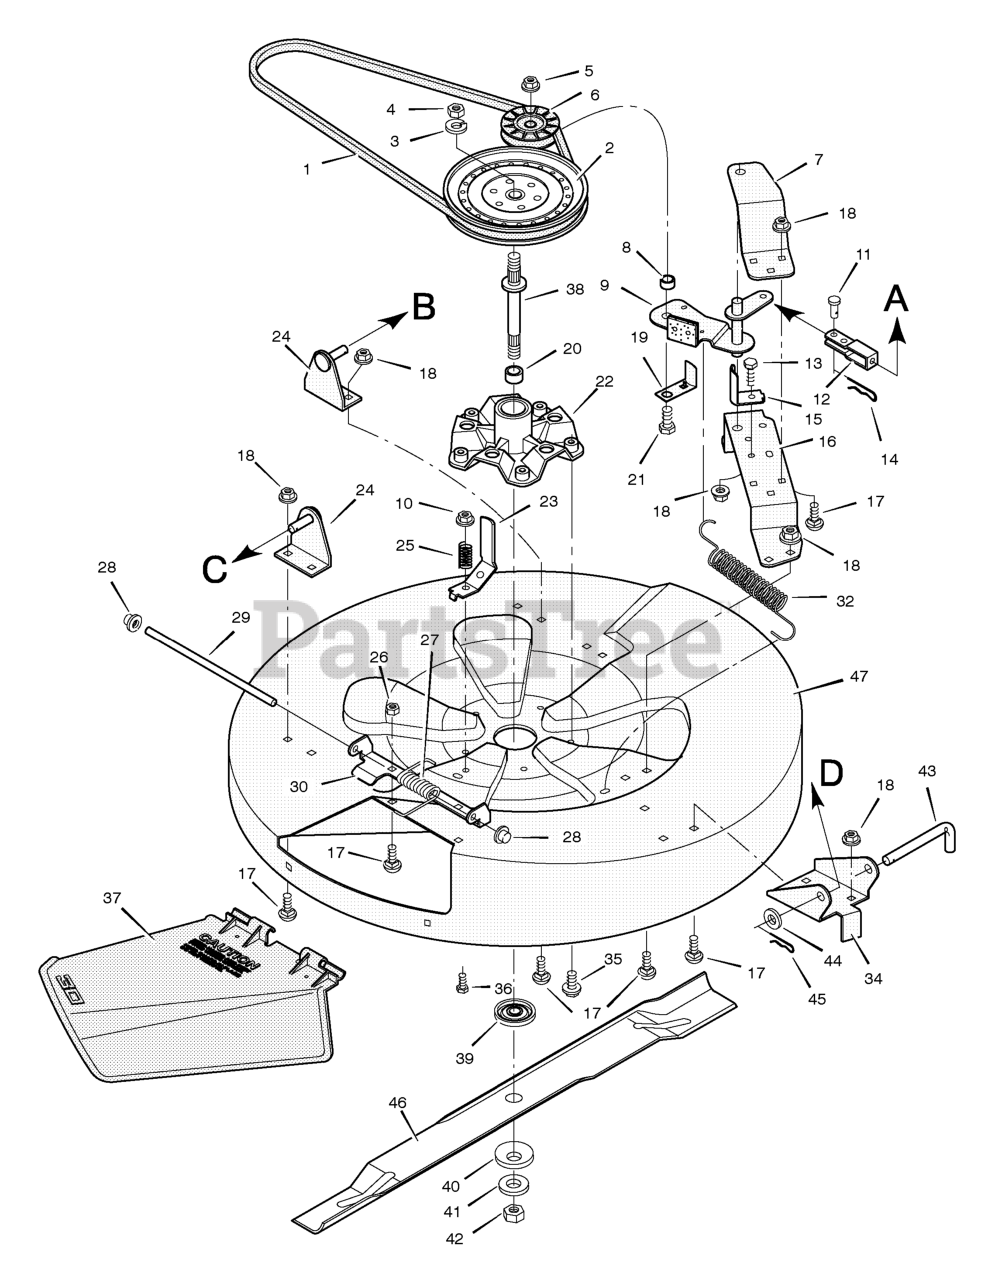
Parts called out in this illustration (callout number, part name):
1	Belt, Mower Drive
2	Pulley, Splined
3	Lockwasher
4	Locknut, Hex
5	Nut, Hex
6	Pulley, Idler
7	Bracket, Upper Idler
9	Assembly, Blade Idler
10	Locknut, Flange
11	Pin, Clevis
13	Bolt, Hex
14	Pin, Hair
15	Guide, Belt
16	Bracket, Lower Idler
17	Bolt, Carriage
18	Nut, Flange
19	Guide, Belt
21	Bolt, Hex
22	Housing, Mandrel
23	Guide, Belt
24	Bracket, Hanger
25	Spring, Compression
26	Nut, Hex
27	Spring - Torsional
28	Push On Cap
30	Hinge, Chute Deflector
32	Spring, Extension
34	Bracket, Front
36	Bolt, Hex
37	Deflector, Chute
38	Mandrel
39	Adapter, Blade
40	Washer, Belleville
41	Washer, Hardened
42	Nut, Hex
43	Pin, Pull
45	Pin, Hair
46	Blade, Standard
